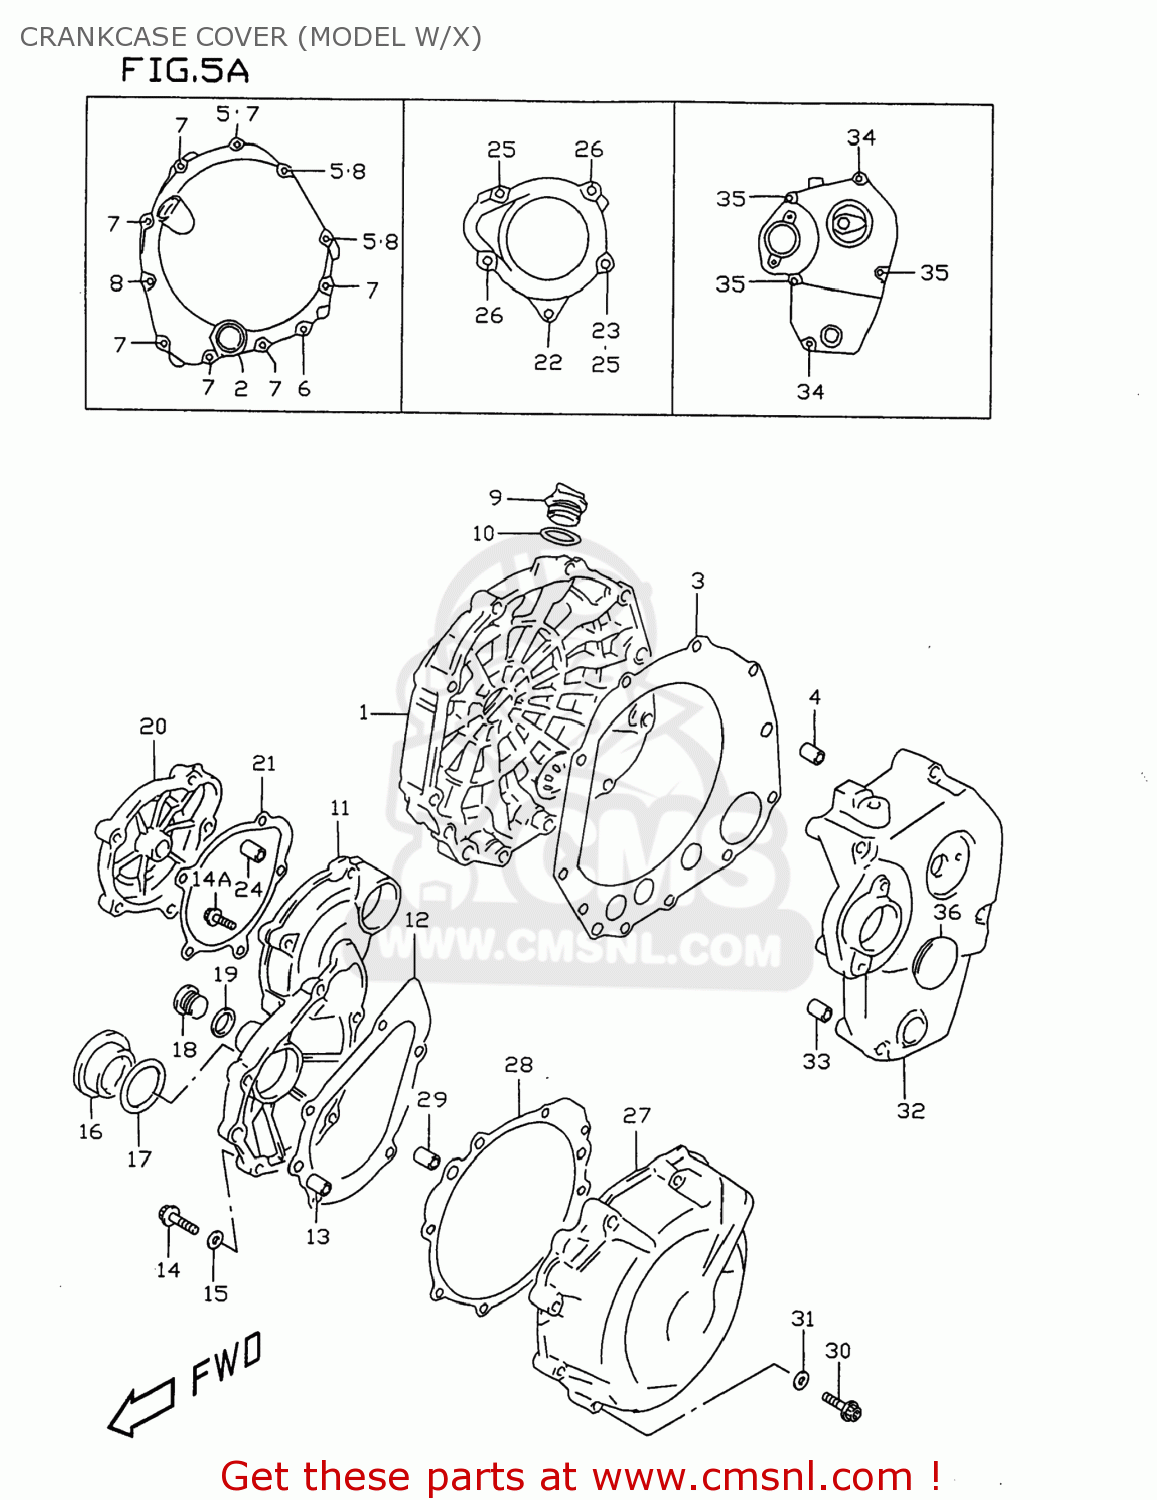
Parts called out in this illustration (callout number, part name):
1	COVER,CLUTCH
2	LENS,OIL LEVEL CHECK
3	GASKET,CLUTCH COVER (NAS)
4	PIN
5	GASKET(5.8X11X1.2) (NAS)
6	BOLT,OIL PAN
7	BOLT
8	BOLT
9	PLUG
10	O RING(D:3.1,ID:16.8)
11	COVER,STARTER CLUTCH
12	GASKET,STARTER CLUTCH COVER
13	PIN
14	BOLT,OIL PAN
14A	BOLT
15	GASKET(5.8X11X1.2) (NAS)
16	PLUG(SILVER)
17	O RING(D:3.1,ID:32.7)
18	PLUG
19	GASKET(16X22X2) (NAS)
20	CAP,STARTER IDLE GEAR
21	GASKET,START IDLE GEAR CAP (NAS)
22	BOLT
23	GASKET(5.8X11X1.2) (NAS)
24	PIN
25	BOLT,OIL PAN
26	BOLT
27	COVER,MAGNETO
28	GASKET,MAGNETO COVER (NAS)
29	PIN
30	BOLT
31	GASKET(5.8X11X1.2) (NAS)
32	COVER,ENGINE SPROCKET
33	PIN
34	BOLT
35	BOLT
36	CAP(OD:36)
